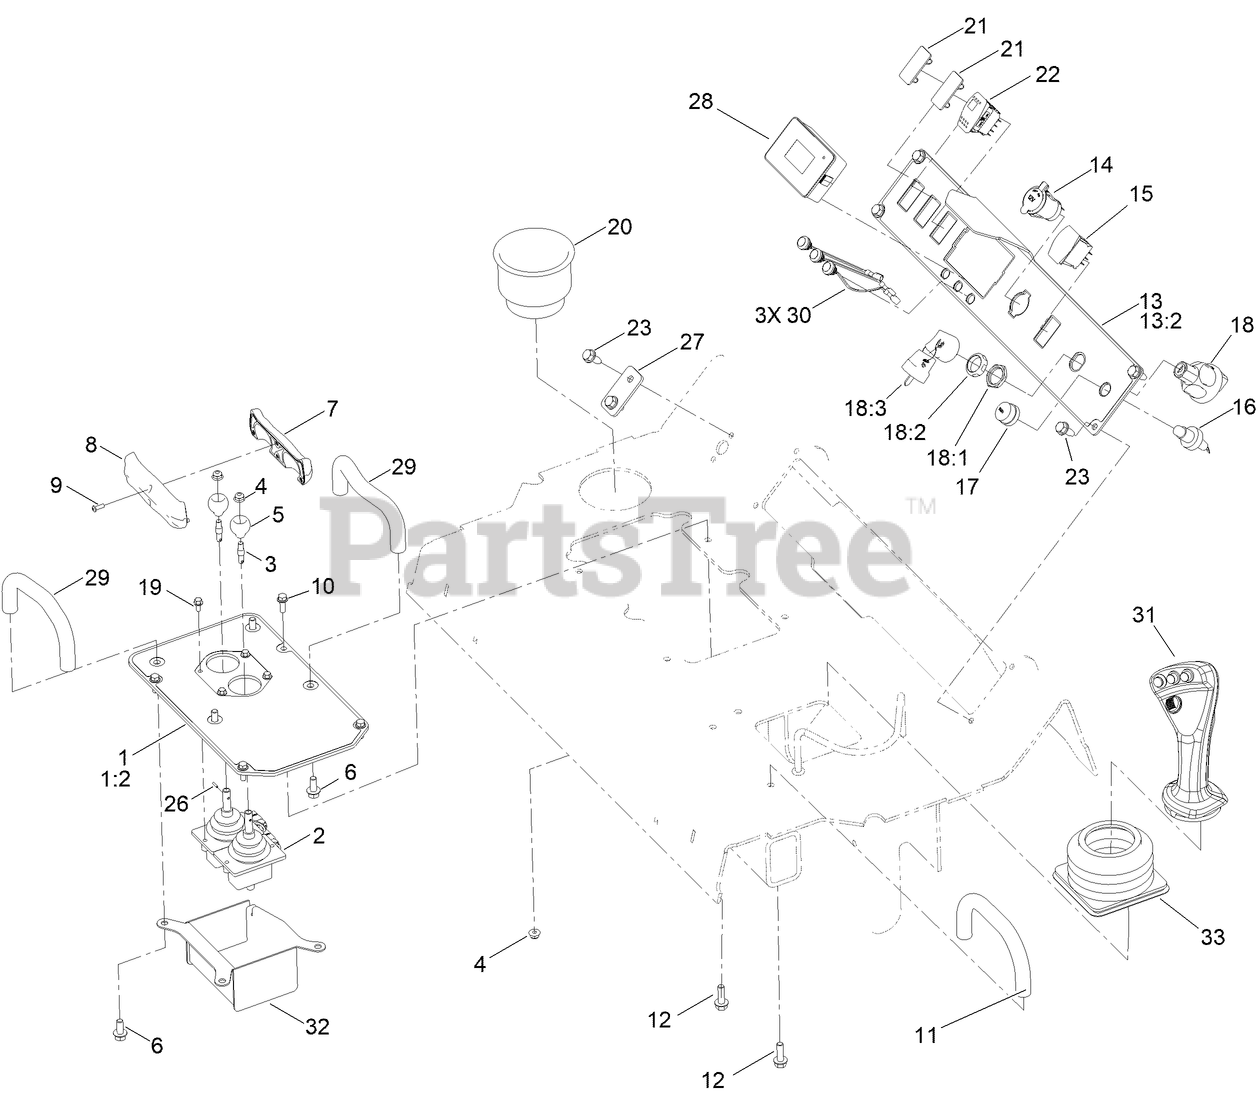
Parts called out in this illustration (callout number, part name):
1	PLATE-CONTROLS, TRACTION
1:2	DECAL-TRACTION
2	LEVER-CONTROL
3	SHAFT-HANDLE
4	NUT-HF
5	BALL-TRACTION
6	SCREW-HHF
7	HANDLE-FRONT
8	HANDLE-REAR
9	SCREW
10	SCREW-HHF
11	BAR-REFERENCE
12	SCREW-HHF
13	PLATE-CONTROL, MAIN
13:2	DECAL-CONTROLS
14	PORT-POWER, 12V
15	SWITCH
16	SWITCH-HORN
17	NUT-WEATHERPROOF
18	IGNITION SWITCH ASM
18:1	NUT-HEX
18:2	NUT-FACE, M22 (PLASTIC)
18:3	SET-KEY, IGNITION
19	SCREW-HFH
20	CUP-HOLDER
21	PLUG-HOLE
22	SWITCH
23	SCREW-HWH
26	PIN-ROLL
27	PLATE-BLANK
28	TDM 2002
29	BAR-REFERENCE
30	SWITCH-PUSHBUTTON
31	HANDLE-JOYSTICK
32	COVER-VALVE
